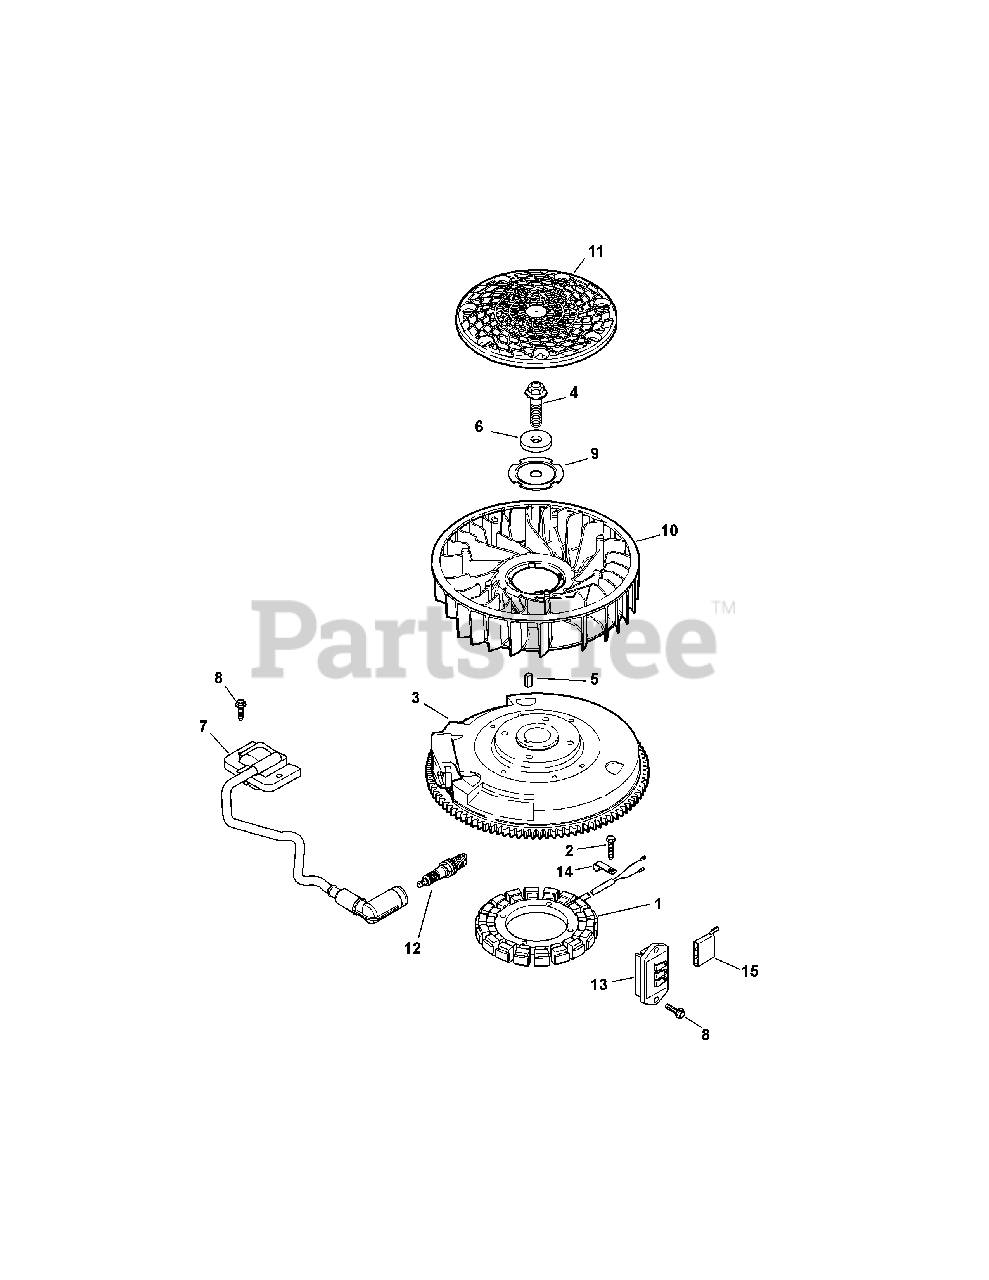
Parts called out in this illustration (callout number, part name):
1	15 Amp Stator Kit
2	Thd. Frm. Screw, M5 X 0.8 X 25
3	Flywheel
4	Screw, Hex Flange
7	Ignition Module
8	Flg. Thd. Frm. Screw, M5 X .8 X 20
9	Fan Mounting Plate
12	Spark Plug
13	Regulator/Rectifier
